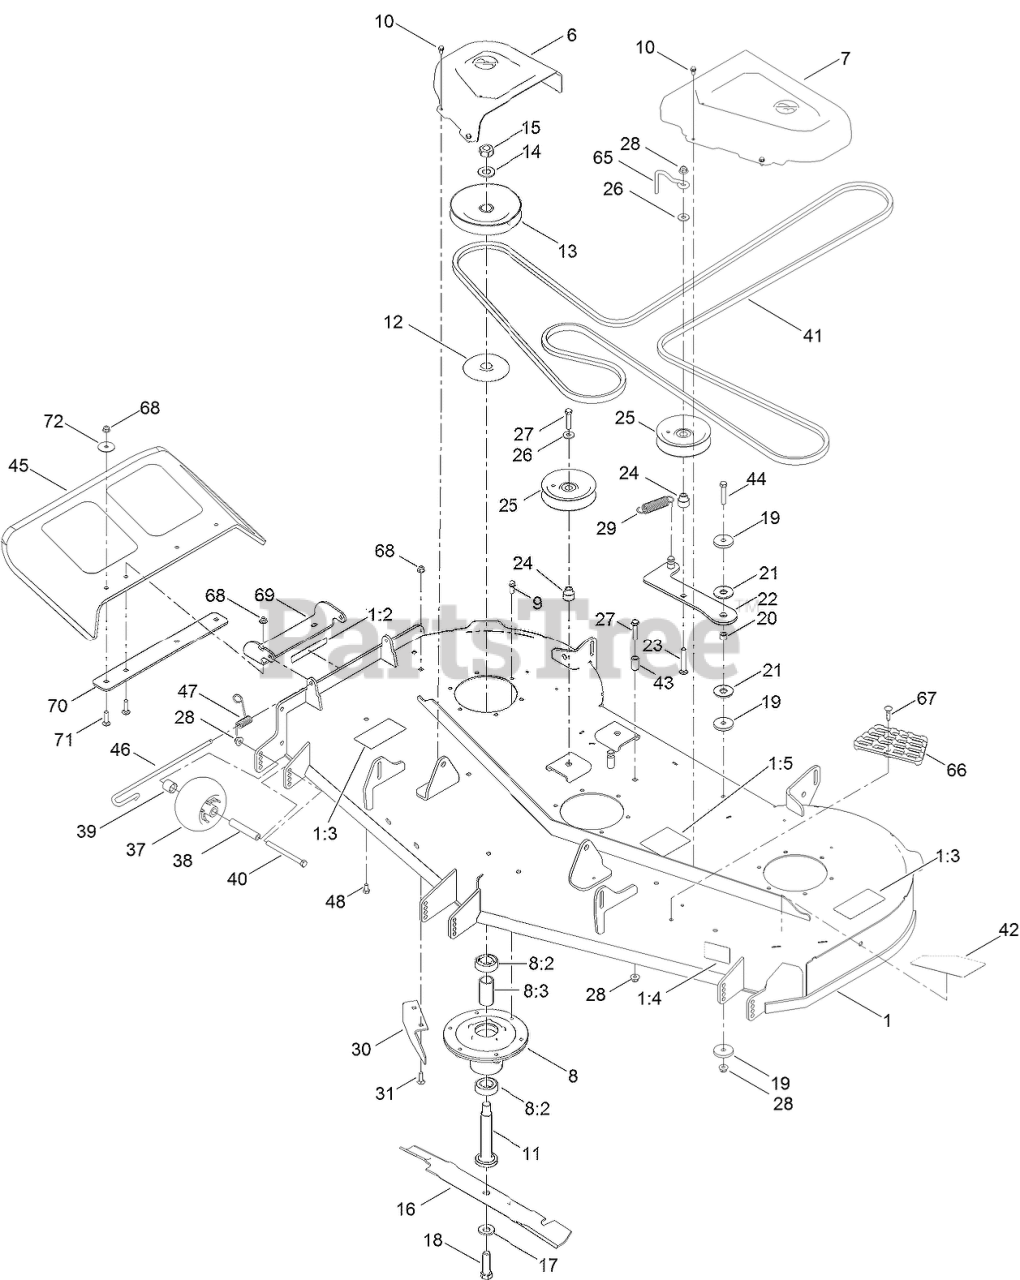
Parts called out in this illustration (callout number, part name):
1	60 INCH DECK ASM
1:2	DECAL-DANGER
1:3	DECAL-DANGER, DECK
1:4	DECAL-SCALP, ANTI
1:5	DECAL-ROUTING, BELT
6	COVER-BELT, RH
7	COVER-BELT, LH
8	SPINDLE ASM
8:2	BEARING-BALL
8:3	SPACER-BEARING
9	SCREW-TAPTITE
10	SCREW-HWH
11	SHAFT-SPINDLE
12	SHIELD-BEARING
13	PULLEY
14	WASHER
15	NUT-HEX
16	BLADE-HI FLOW, 20.5 INCH
17	WASHER-BELLEVILLE
18	SCREW-BLADE
19	WASHER-PLAIN
20	SPACER
21	WASHER-FRICTION, COMPOSITE
22	IDLER ARM ASM
23	SCREW-CARR
24	BUSHING-IDLER
25	PULLEY-IDLER, FLAT
26	WASHER-HARDENED
27	SCREW-HH
28	NUT-HF, NI
29	SPRING-EXTENSION
30	BAFFLE-CUTOFF
31	SCREW-CARR
37	ROLLER-SCALP, ANTI
38	TUBE-SPANNER
39	SPACER-AXLE, REAR
40	SCREW-HH
41	V-BELT
42	DECAL - DECK
43	SPACER-FENDER
44	SCREW-HH
45	DEFLECTOR
46	PIN-CHUTE
47	SPRING-TORSION
48	SCREW-HH
65	GUIDE-BELT, IDLER
66	STEP-DECK
67	BOLT-CARRIAGE
68	NUT-HF, NI
69	BRACKET-DEFLECTOR, UPPER
70	PLATE-DEFLECTOR
71	SCREW-CARR
72	WASHER-FLAT
